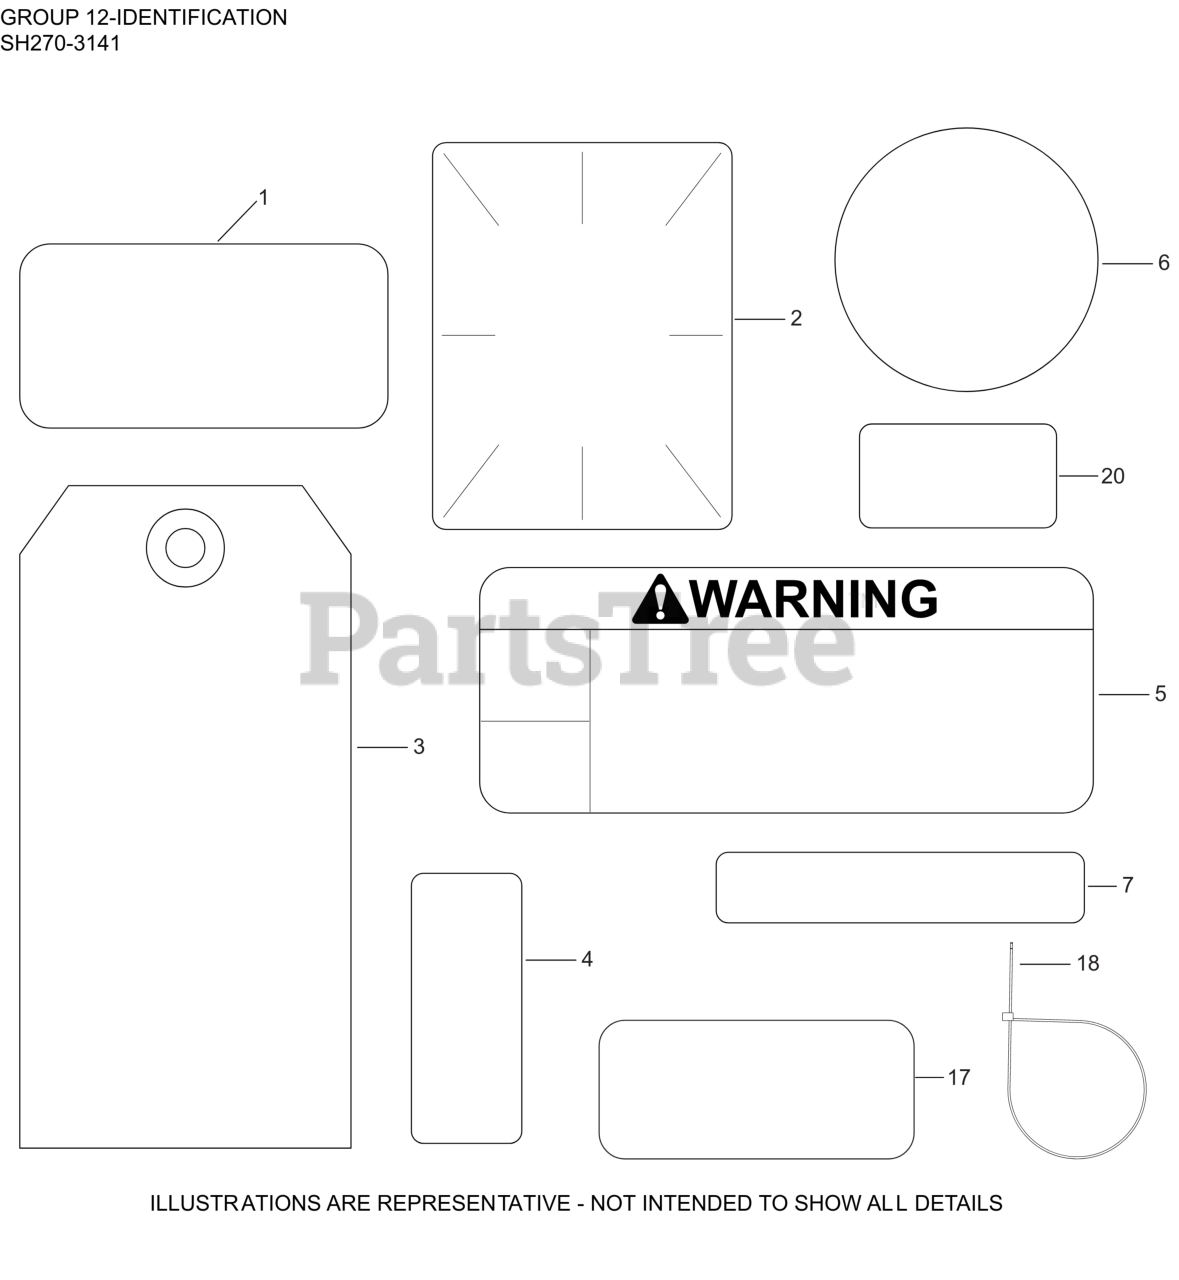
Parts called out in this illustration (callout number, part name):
1	LABEL, MAINTENANCE (CKY)
2	LABEL, CLEAR LAMINATION
3	TAG, HANG
3	TAG, PROP 65-OIL FILL ASSEMBLED
4	DECAL, FUEL/CHOKE - ON/OFF
5	DECAL, WARNING
6	LABEL, RECOIL 75MM
7	DECAL, THROTTLE
17	DECAL, ETHANOL WARNING
20	LABEL, HP SH270
